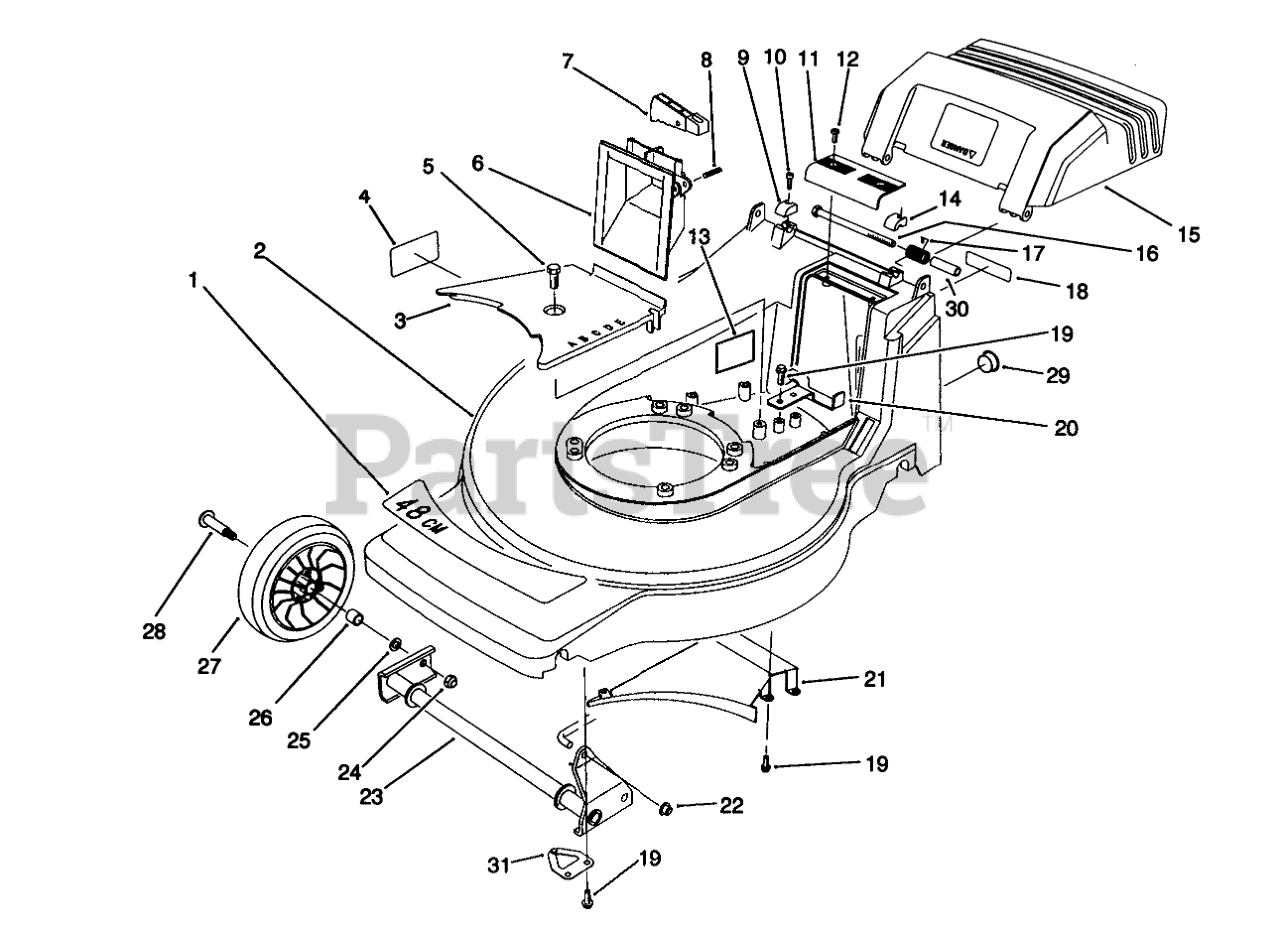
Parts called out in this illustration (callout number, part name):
1	DECAL - DECK
2	Housing-48cm (Incl. Ref. #1, 4, & 13)
3	BELT COVER
4	Decal Danger
5	SCREW-HWHTF
6	GRIP - LOWER
7	TRIGGER - HOC
8	PIN-SPIRAL
9	CAP-HINGE BOLT, RH
10	SCREW-HSH
11	GRIP-UPPER
12	SCREW-PPH, PLASTITE
13	Decal-Noise
14	CAP-HINGE BOLT, LH
15	Door-Discharge
16	SCREW-HH
17	DOOR SPRING
18	DECAL FRENCH REGUL.
19	SCREW-HWH
20	REAR BELT GUIDE
21	Ramp-Discharge
22	NUT-PUSH
23	FRONT PIVOT WA
24	NUT-HEX
25	WASHER
26	BUSHING
27	Wheel & Tire Assembly (Incl. Ref. #26)
28	BOLT-WHEEL
29	DOME PLUG (DP-1000)
30	SPACER-DOOR
31	LH AXLE RETAINER
